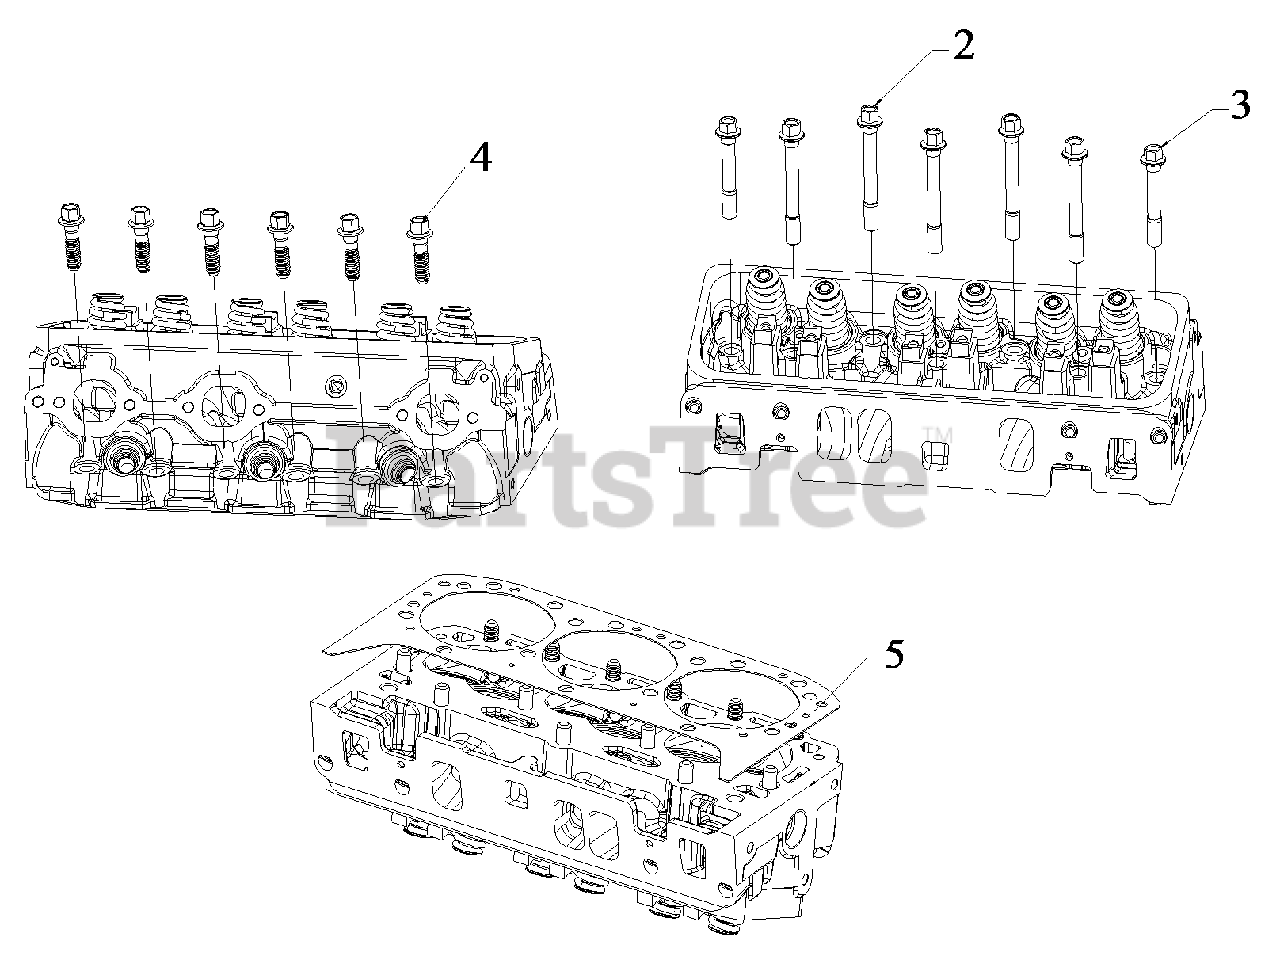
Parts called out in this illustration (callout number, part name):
2	BOLT
3	BOLT
4	BOLT
5	GASKET, CYLINDER HEAD
